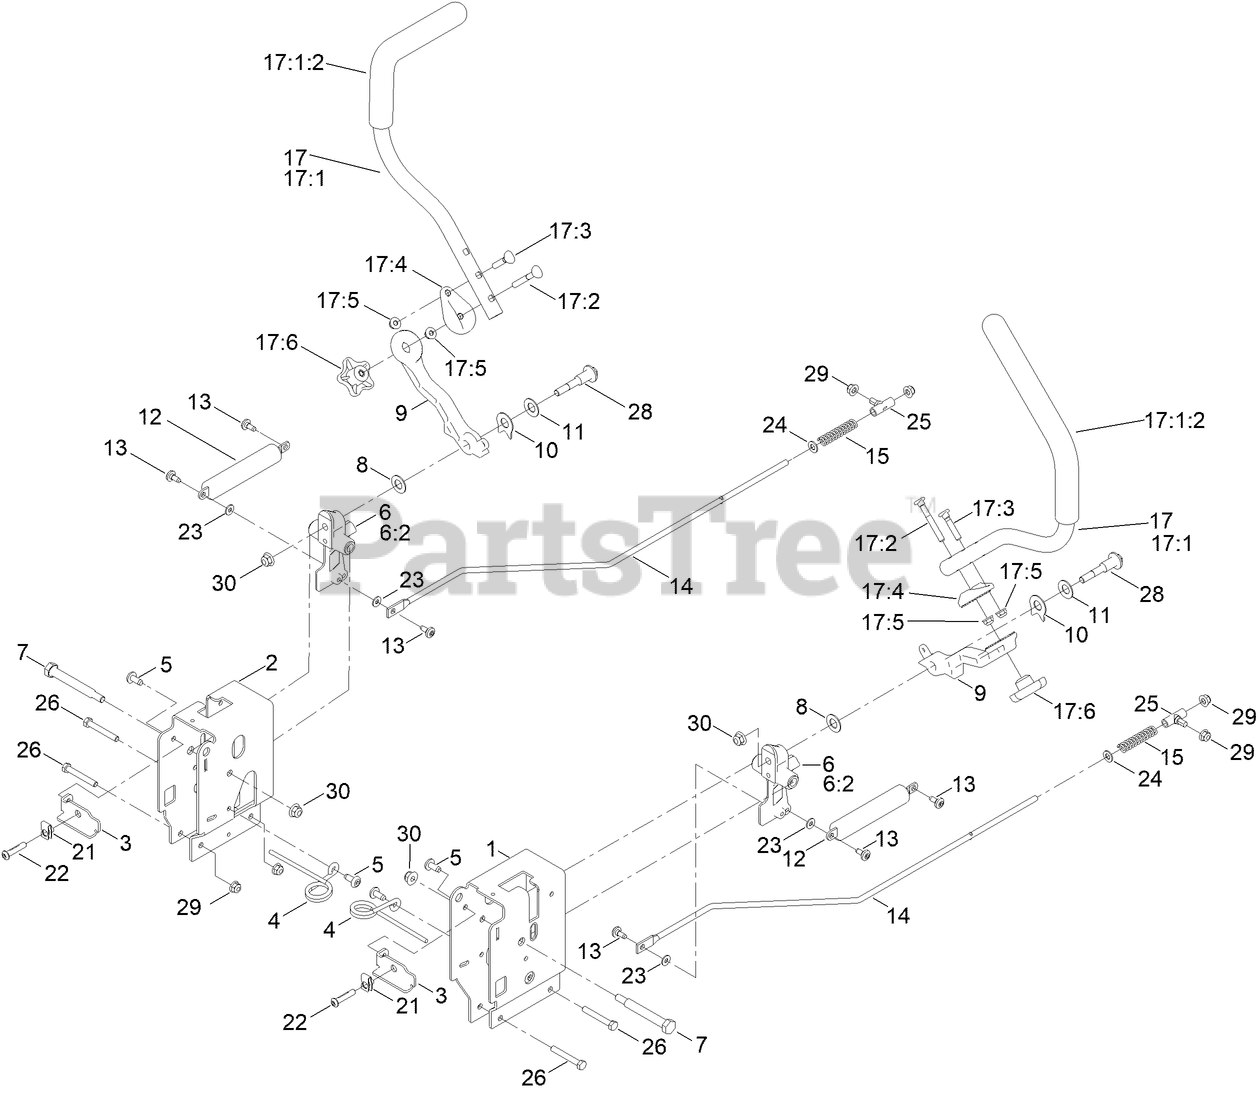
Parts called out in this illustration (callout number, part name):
1	CONTROL BOX - LH G7
2	CONTROL BOX - RH G7
3	ADJUSTMENT PLATE-CONTROL BOX
4	SPRING-TORSION
6	PIVOT ARM ASM
6:2	BUSHING-FLANGE
7	BOLT-PIVOT
8	WASHER-NYLON
9	ARM-CONTROL, 32 TEETH
10	SPACER, ANTI-ROTATION
11	WASHER-BELLEVILLE
12	DAMPER-NON CAVITATING
13	SCREW-SHOULDER
14	ROD - HYDRO, LH
15	SPRING-COMPRESSION
17	HANDLE-CONTROL, ASM
17:1	HANDLE-CONTROL,
17:2	SCREW-HANDLE
17:3	SCREW-HANDLE
17:4	DISC-ADJUSTMENT HANDLE, 32 TEETH
17:5	NUT-HF
17:6	KNOB-HANDLE
22	SCREW-HSBH
23	WASHER
24	WASHER-PLAIN
25	MOUNT-ROD, HYDRO
26	SCREW-HH
28	BOLT-PIVOT
29	NUT-HF, NI
30	NUT-HF, NI
